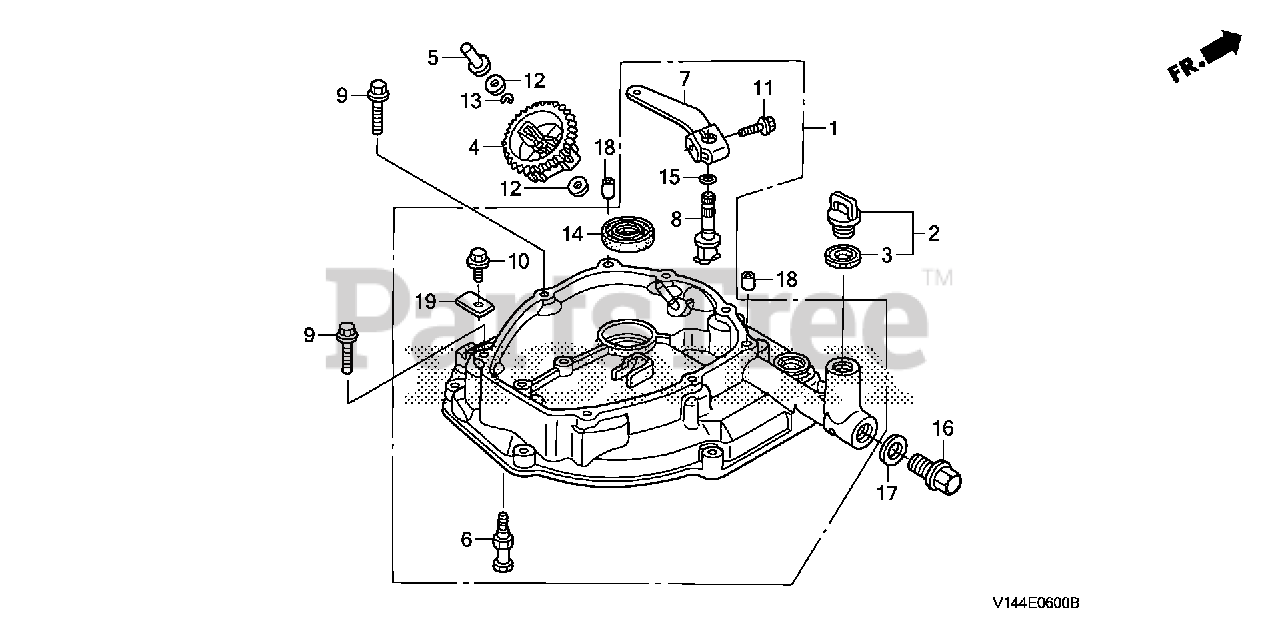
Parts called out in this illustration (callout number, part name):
1	COVER, CRANKCASE
2	CAP ASSY., OIL FILLER
3	GASKET, OIL FILLER CAP
4	GOVERNOR ASSY.
5	SLIDER, GOVERNOR
6	PIN, ANCHOR
7	ARM, CLUTCH
8	CAM, CLUTCH
9	BOLT, FLANGE (5X23)
10	BOLT, FLANGE (6X12) (CT200)
11	BOLT, FLANGE (5X25)
12	WASHER (4.2X13)
13	CLIP, GOVERNOR HOLDER
14	OIL SEAL (19X30X5)
15	O-RING (6.8X1.9)
16	BOLT, DRAIN PLUG (20MM)
17	WASHER, DRAIN PLUG (20MM)
18	PIN A, DOWEL (6X10)
19	STOPPER, CABLE
